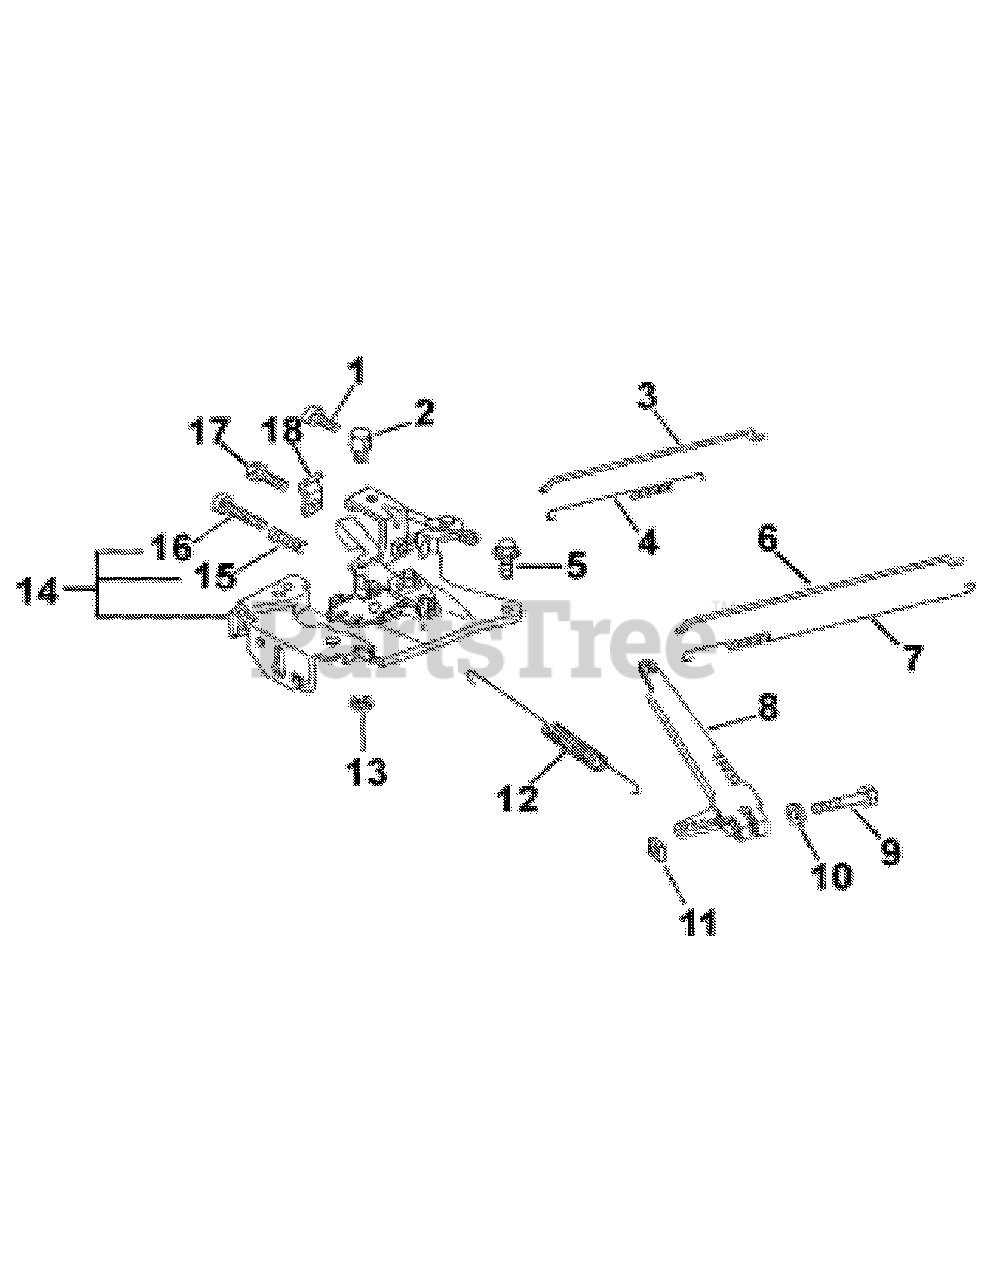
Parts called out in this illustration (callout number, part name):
1	Pan Head Screw
3	Choke Linkage
4	Linkage Spring
6	Throttle Linkage
7	Linkage Spring
8	Governor Lever
12	Governor Spring
14	Throttle Lever
15	Compression Spring
16	Pan Head Screw
